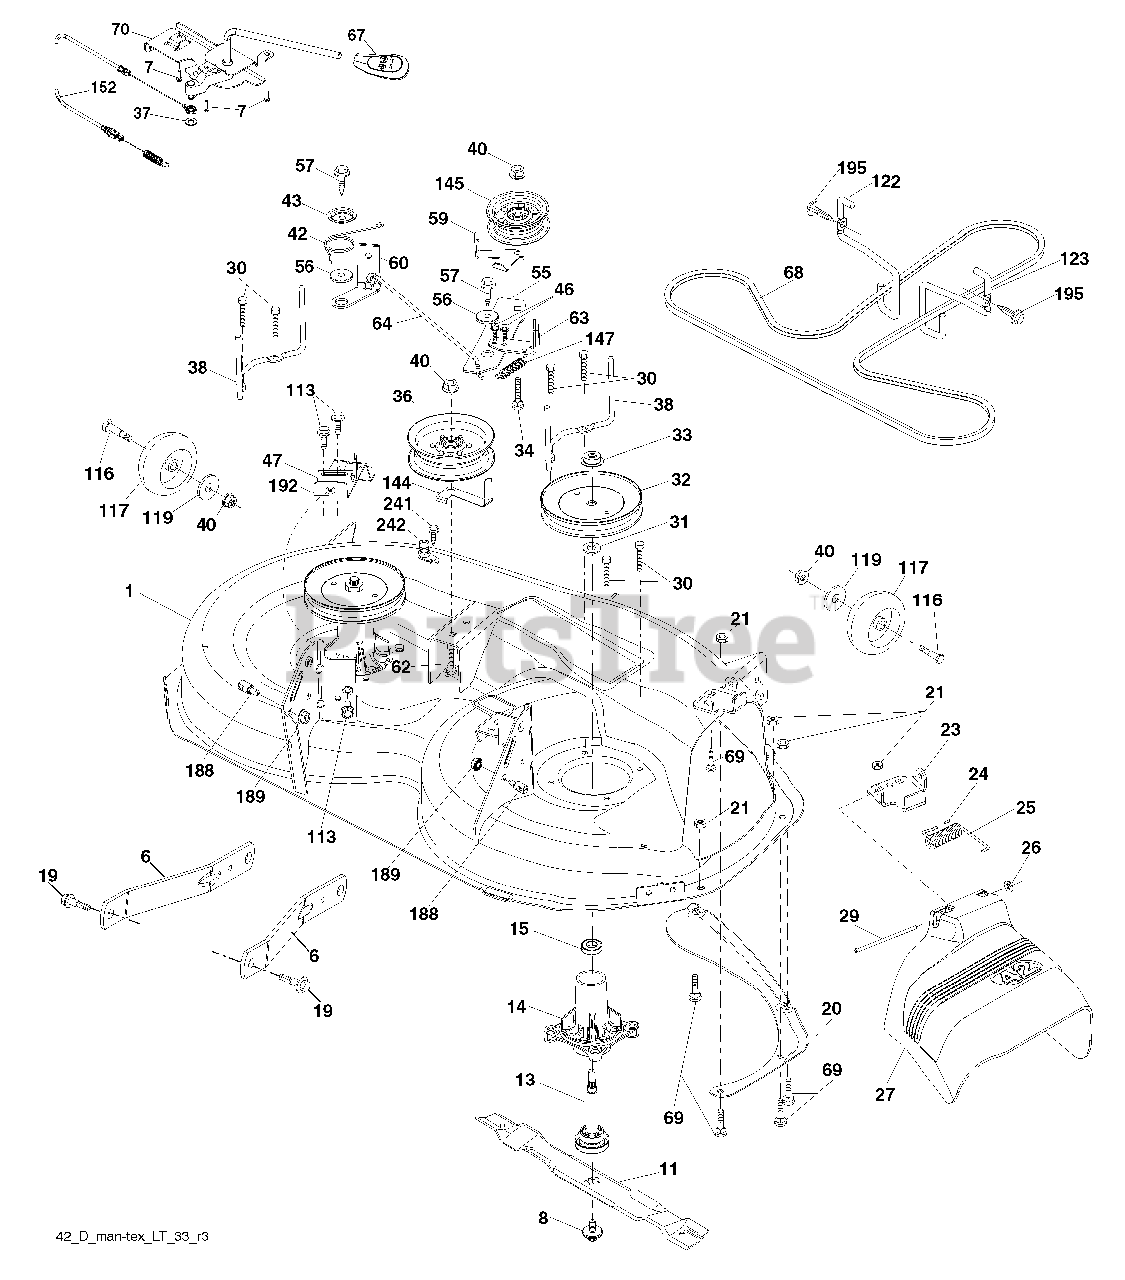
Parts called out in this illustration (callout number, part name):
1	Mower Housing
2	Cover Mandrel RH
3	Cover Mandrel LH
6	Arm Suspension
7	Screw # 10 x 0.750
8	Bolt/Washer asm 7/16-20 unf
11	Blade Mower Hi Lift
13	Shaft Assembly, Mandrel
14	Housing, Mandrel
15	Bearing, Ball, Mandrel
19	Bolt, Shoulder
21	Nut
23	Bracket, Deflector
24	Cap, Sleeve
25	Spring, Torsion, Deflector
27	Shield, Deflector
29	Rod, Hinge
30	Screw Thdrol Rolling Wsh Hd
31	Washer, Spacer
32	Pulley, Mandrel
33	Nut, Toplock, Flanged
34	Bolt Carr Sh. 3/8-16 x 1-1/2 Gr. 5
36	Pulley, Idler, Flat
37	Washer 13/32 x 13/16 x 16 Ga.
38	Keeper Belt LH Mandrel
40	Nut, Lock Flg. 3/8-16 unc
42	Spring Torsion Brake
43	Spring Torsion Retainer
47	Bracket Clutch Cable
55	Arm, Idler
56	Spacer, Retainer
57	Screw Hexwsh Thd 3/8-16 x 1
59	Guard, Tuv Idler (94)
60	Arm Brake Mower LH
63	Arm Brake Mower
64	Linkage Brake
67	Handle, Clutch Cable
68	V-Belt
69	Bolt
70	Clutch Asm. Cable
113	Screw 5/16-18
116	Bolt, Shoulder
117	Wheel, Gauge
119	Washer 13/32 x 1-1/4 x 12 Ga.
122	Keeper Belt Eng. LH
123	Keeper Belt Eng. RH
144	Keeper Belt
145	Pulley Idler
147	Spring Return
152	Cable Clutch Manual w/Spr.
188	Stud Fastener
189	Nut Lock Hex Flange
195	Screw 3/8-16 x 3/4
197	Washer 13/32 x 13/16 x 12 Ga.
198	Baffle Center Front
199	Baffle Front RH
200	Washer 13/32 x 1 x 1/2 11 Ga.
240	Bolt 3/8-16 unc x 2-1/4 Gr. 5
242	Washout Port
